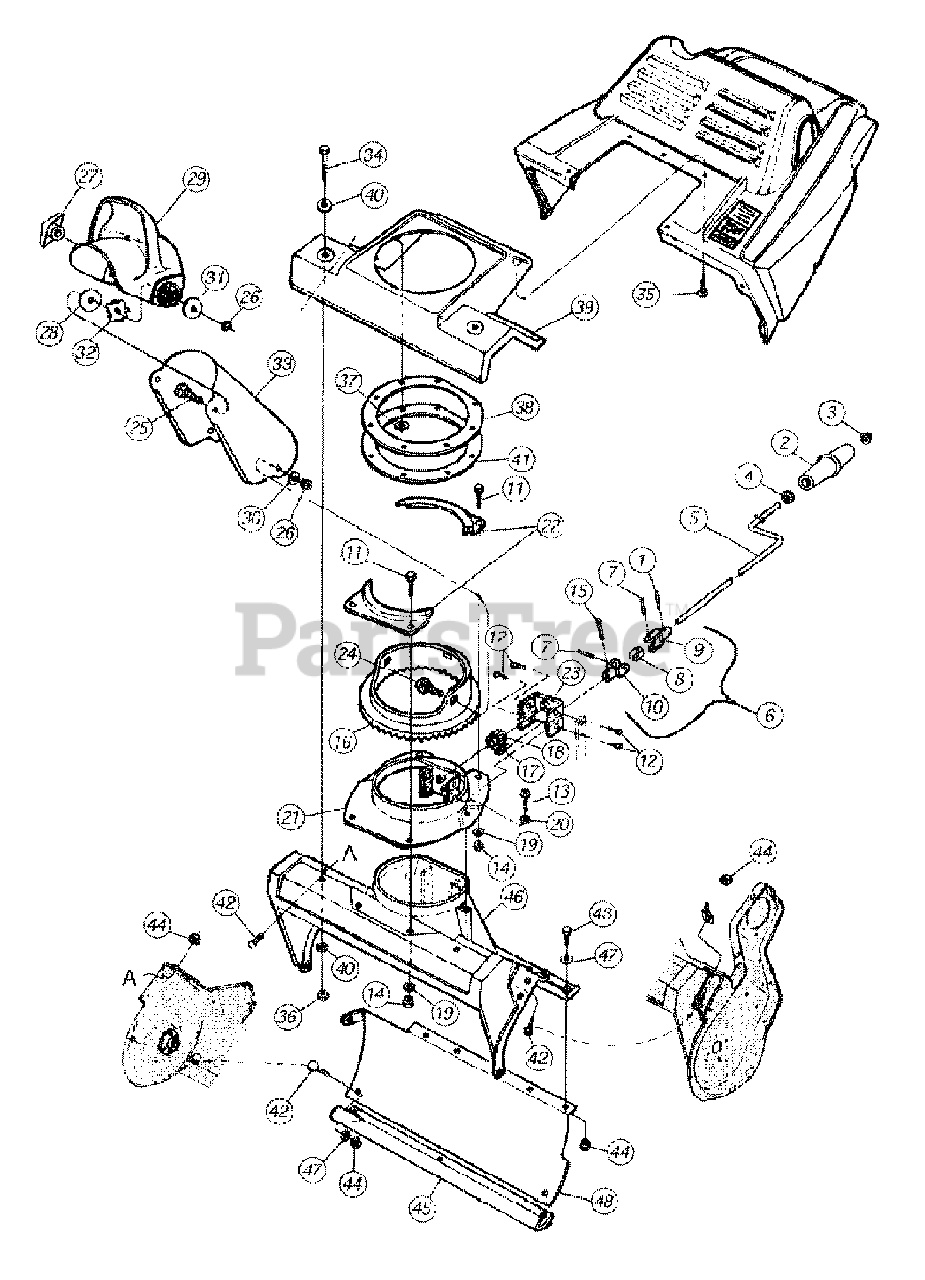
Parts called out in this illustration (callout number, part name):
1	Pin, Roll: 1/8 x .63
2	Chute Rotating Knob
3	Push Cap
4	Flat Washer
5	Chute Crank
6	U-Joint Assembly
7	Pin, Roll: 5/32 x .88
8	Connector, U-Joint
9	Clevis, Rear U-Joint
10	Clevis, Front U-Joint
11	Hex Screw: 1/4-20 x .75 Gr 5
12	Hex Screw: 1/4 x .50
13	Hex Screw
14	Sems Nut: 1/4-20
15	Cotter Pin: 1/8 dia x 1.25
16	Chute Base: Black
17	Gear, Drive
18	Gear, Idler
19	Flat Washer
20	Flat Washer
21	Plate, Chute Base
22	Retainer, Chute Base
23	Mounting Bracket
24	Carriage Bolt
25	Carriage Screw: 5/16-18 X 1.0
26	Hex Lock Nut: 5/16-18
27	Knob Assembly
28	Rubber Washer: .50 X 1.50 X .08
29	Chute Deflector
30	Flat Washer
31	Flat Washer
32	Washer, Octagon
35	Tap Screw
36	Sems Nut: 1/4-20
37	Nut, Push On
38	Chute Gasket
39	Chute Base Cover
40	Flat Washer
41	Retainer, Gasket
42	Carriage Bolt: 1/4-20 X .75
43	Hex Screw: 1/4-20 x .75 Gr 5
44	Sems Nut: 1/4-20
45	Shave Plate
46	Auger Housing
47	Flat Washer
